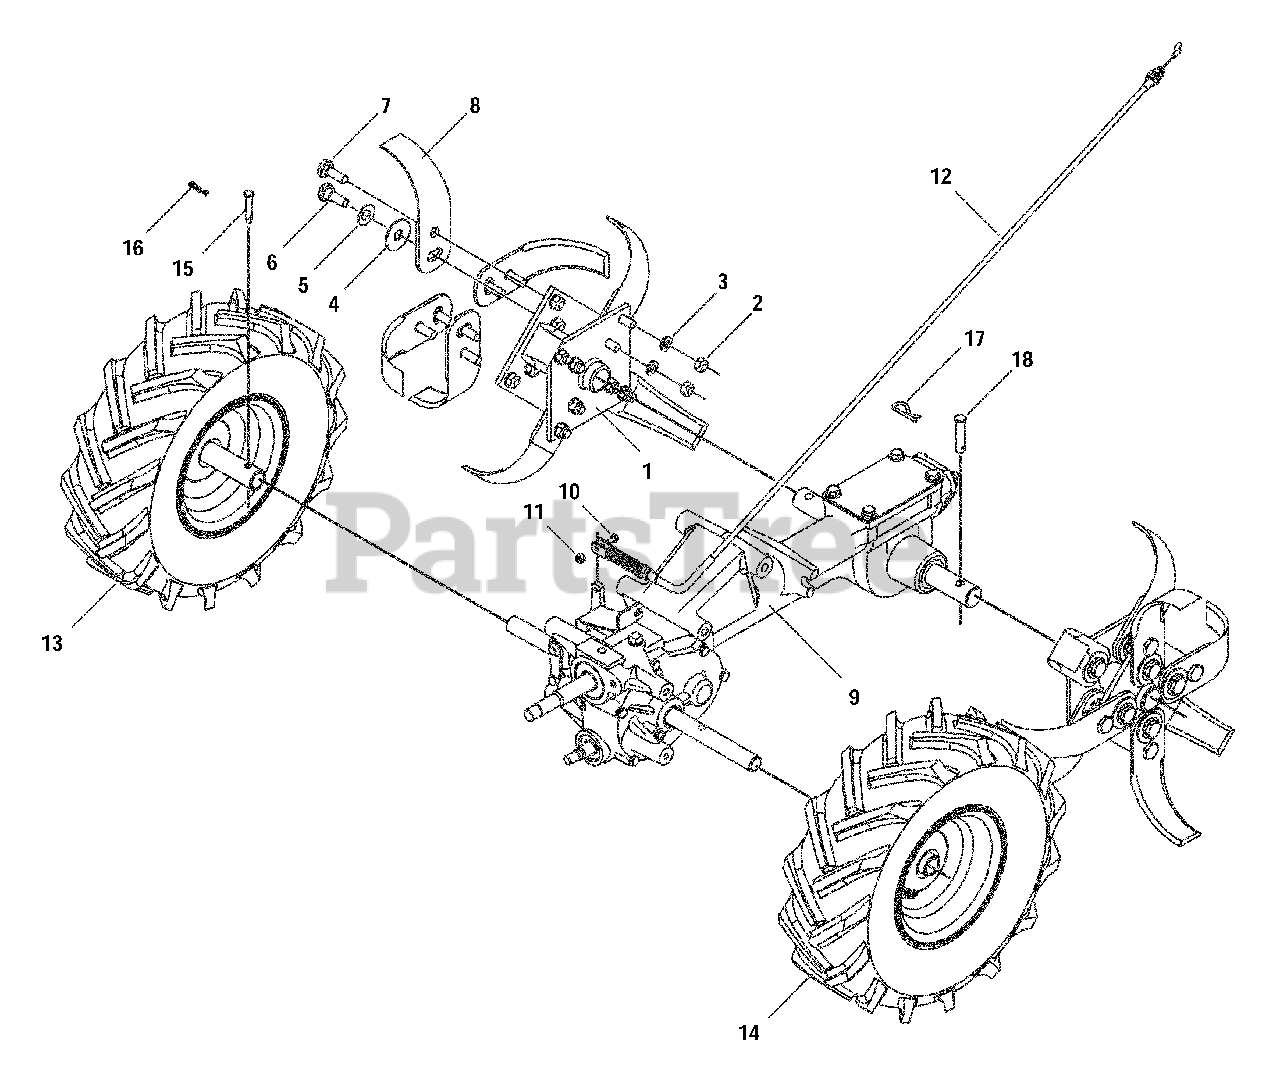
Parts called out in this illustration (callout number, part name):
1	Adapter Assembly, Tine
2	Nut, 3/8-24, Hex, Lock
3	Washer, Lock, 3/8, Regular Duty
4	Washer, Flat,.51 x 1.5 x.07
5	Washer, Bell,.525 x 1.00 x.050
6	Screw, Shld 1/2 Dia x.325
7	Screw, Shld 1/2 Dia x.180, 3/8-2
9	Transmission Assembly, Dual Direction
10	Screw, Machine, #10-24, 1.00, Gr5
11	Nut, Hex Lock, #10-24, Gr2, Nylon
12	Cable, Shift, Wheel
13	Wheel, Complete, 14 x 4.5 x 6, RH, Gray
14	Wheel, Complete, 14 x 4.5 x 6, LH, Gray
15	Pin, Clevis,.250 x 1.53
16	Pin, Cotter,.072 Dia. x 1.13 Lg
17	Internal Cotter Pin
18	Pin, Clevis, 3/8, 1.75
